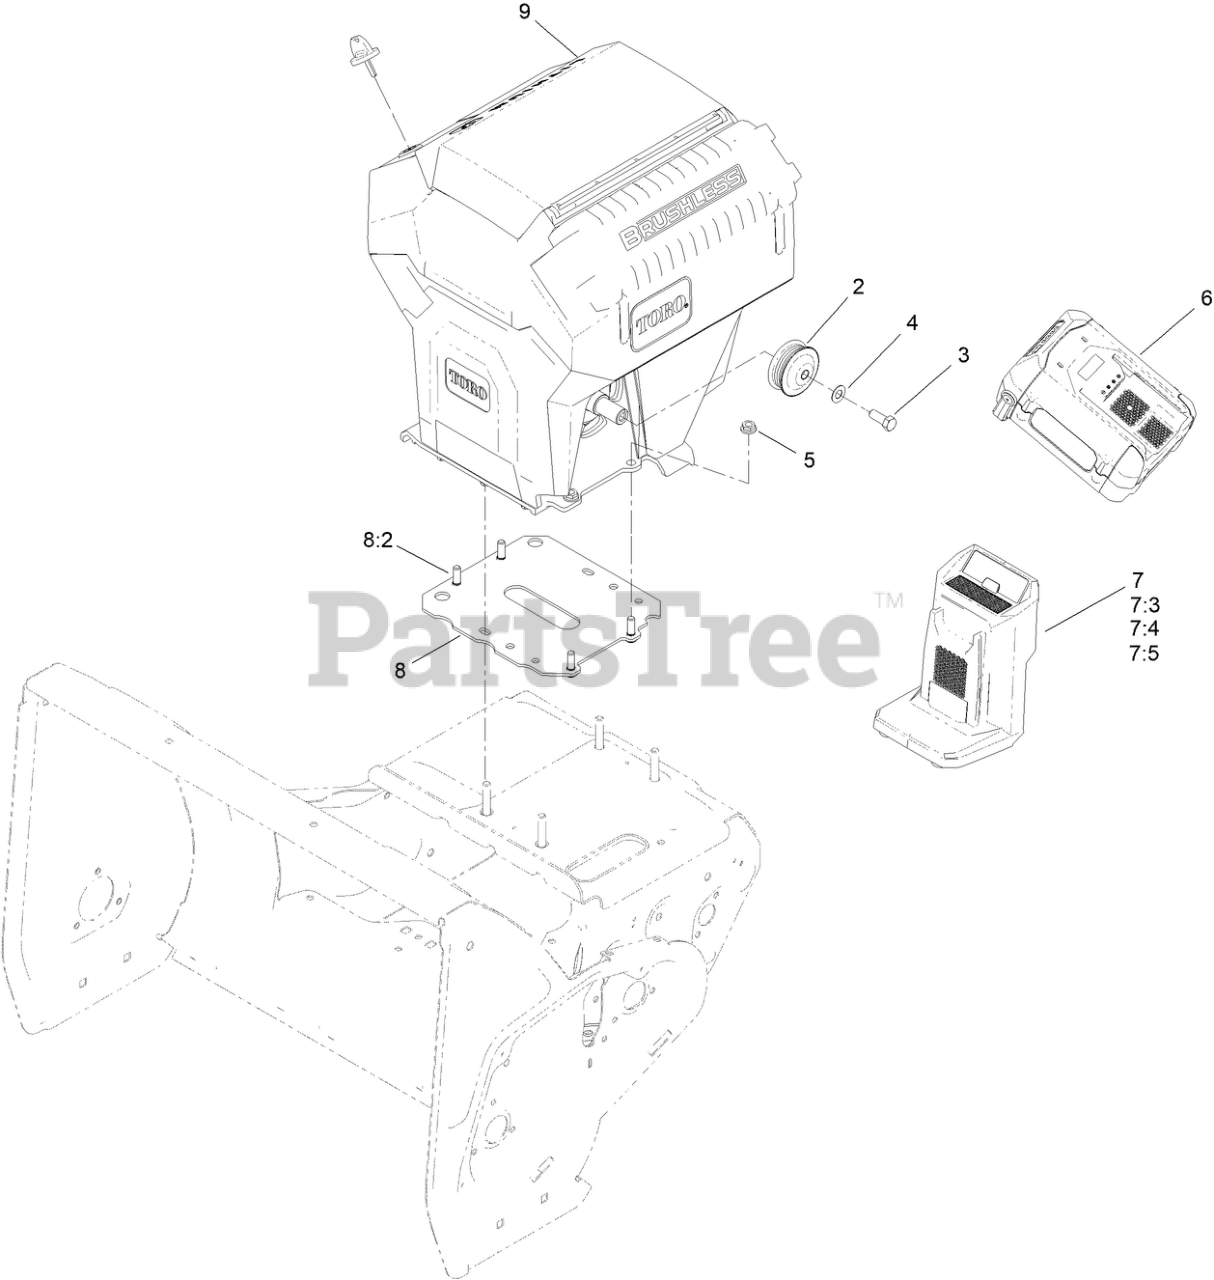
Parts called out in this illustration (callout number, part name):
2	PULLEY-ENGINE
3	SCREW-HH
4	WASHER-HARDENED
5	NUT-HF
6	BATTERY-LI-ION, 60V 6.0AH, PROD, CE
7:3	CORD-CHARGER, AU/NZ
7:4	CORD-CHARGER, CE
7:5	CORD-CHARGER, UK
8	ADAPTER ASM
8:2	STUD-PRESS
9	POWERHEAD- 60V SNOWMASTER
